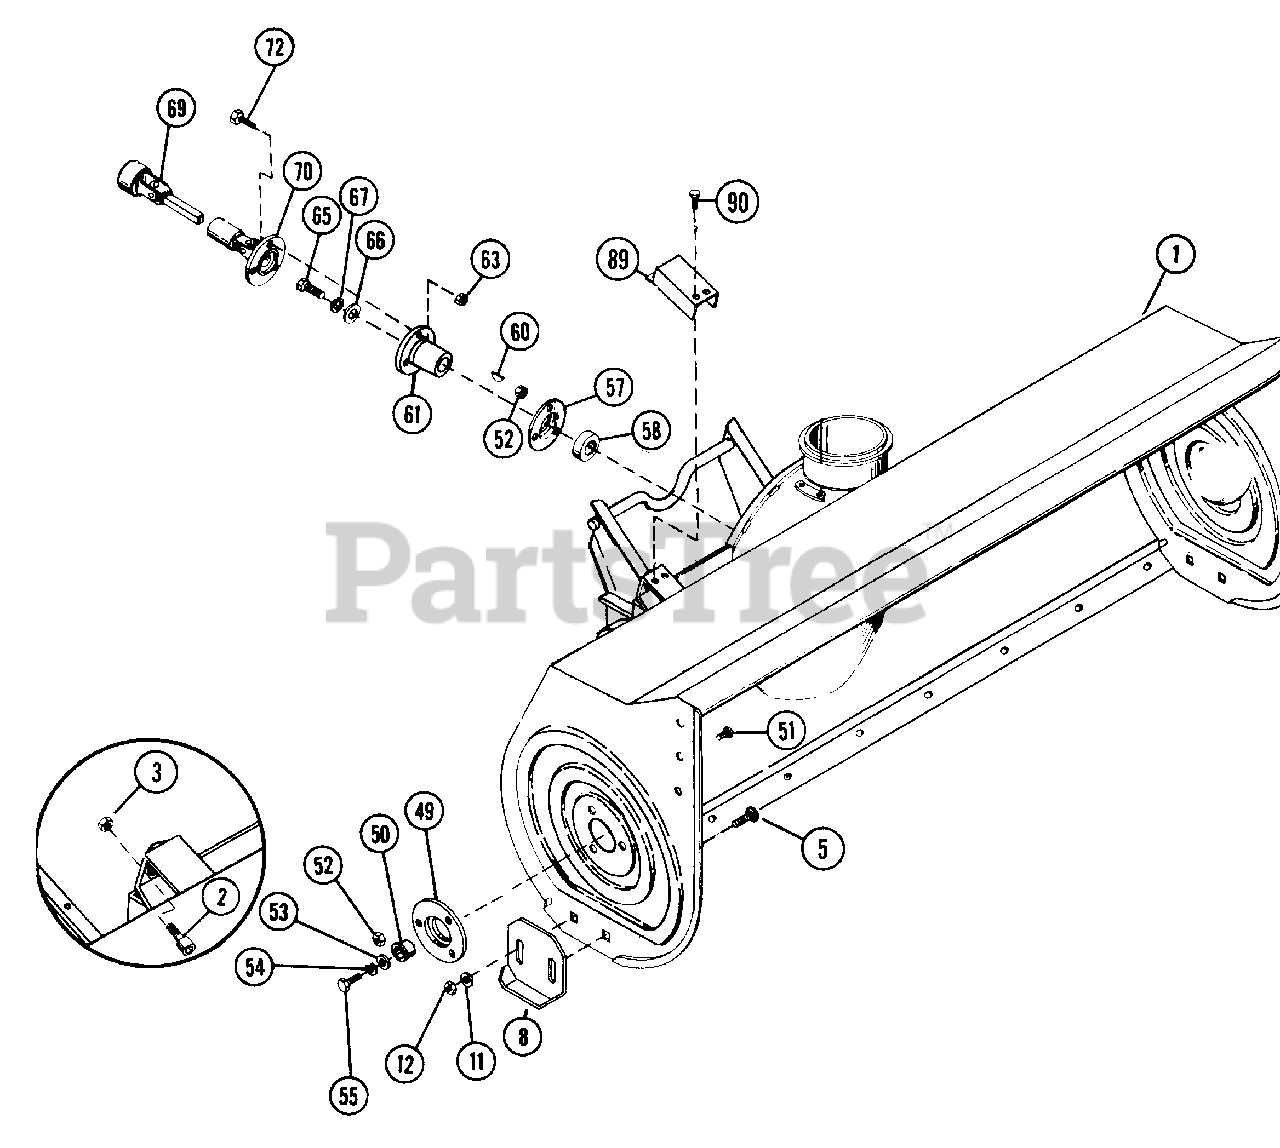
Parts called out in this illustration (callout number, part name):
1	48" SNO THRO HOUSING
2	SCREW, 10-24X.375 CAP
3	NUT, LOCK 10-24
5	BOLT, CARRIAGE 3/8-16X.75
8	RUNNER, SKID SHOE
11	WASHER, FLAT .406X.812X.065
12	NUT, LOCK 3/8-16
49	SUPPORT, BEARING
50	BUSHING, FLANGE 1X1.12X.625
51	BOLT, RIB NECK 1/4-20X.5
52	NUT, LOCK 1/4-20
53	WASHER, FLAT .515X1.441X.1
54	WASHER, LOCK 3/8 SP. HEAVY
55	BOLT, HEX 1/2-13X1
57	BEARING, FLANGE
58	BEARING, BALL
60	KEY, WOODRUFF 3/16X7/8 HRD #11
61	HUB, SNOWBLOWER
63	NUT, LOCK 1/4-20
65	BOLT, HEX 3/8-16X1.00
66	WASHER, FLAT .438X1.000X.083
67	WASHER, LOCK 3/8 REG.
69	UNIVERSAL SHAFT
70	UNIVERSAL PLATE HALF
72	BOLT, HEX 1/4-20X1.00
90	TAPTITE, 1/4-20X.375
